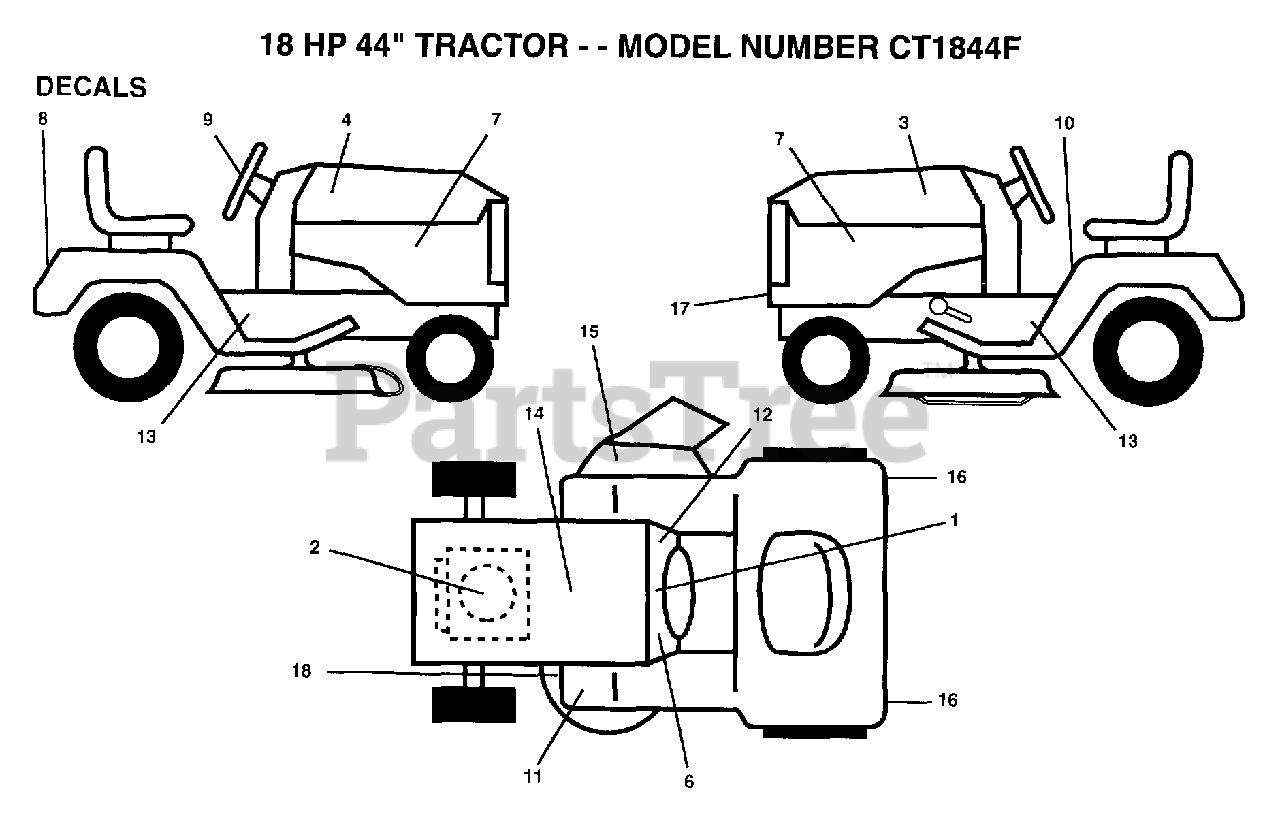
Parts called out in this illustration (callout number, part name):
2	DECAL.ENG.272559
3	DECAL.STRIPE.HOOD
7	DECAL.HOOD.INSERT
8	DECAL.FENDER
9	DECAL.STG.WHL.INS
10	DECAL CAUTION
11	DECAL T
14	DECAL
15	"DECAL, WARNING"
16	REFLECTOR-TAIL YT
17	DECAL.GRILLE
